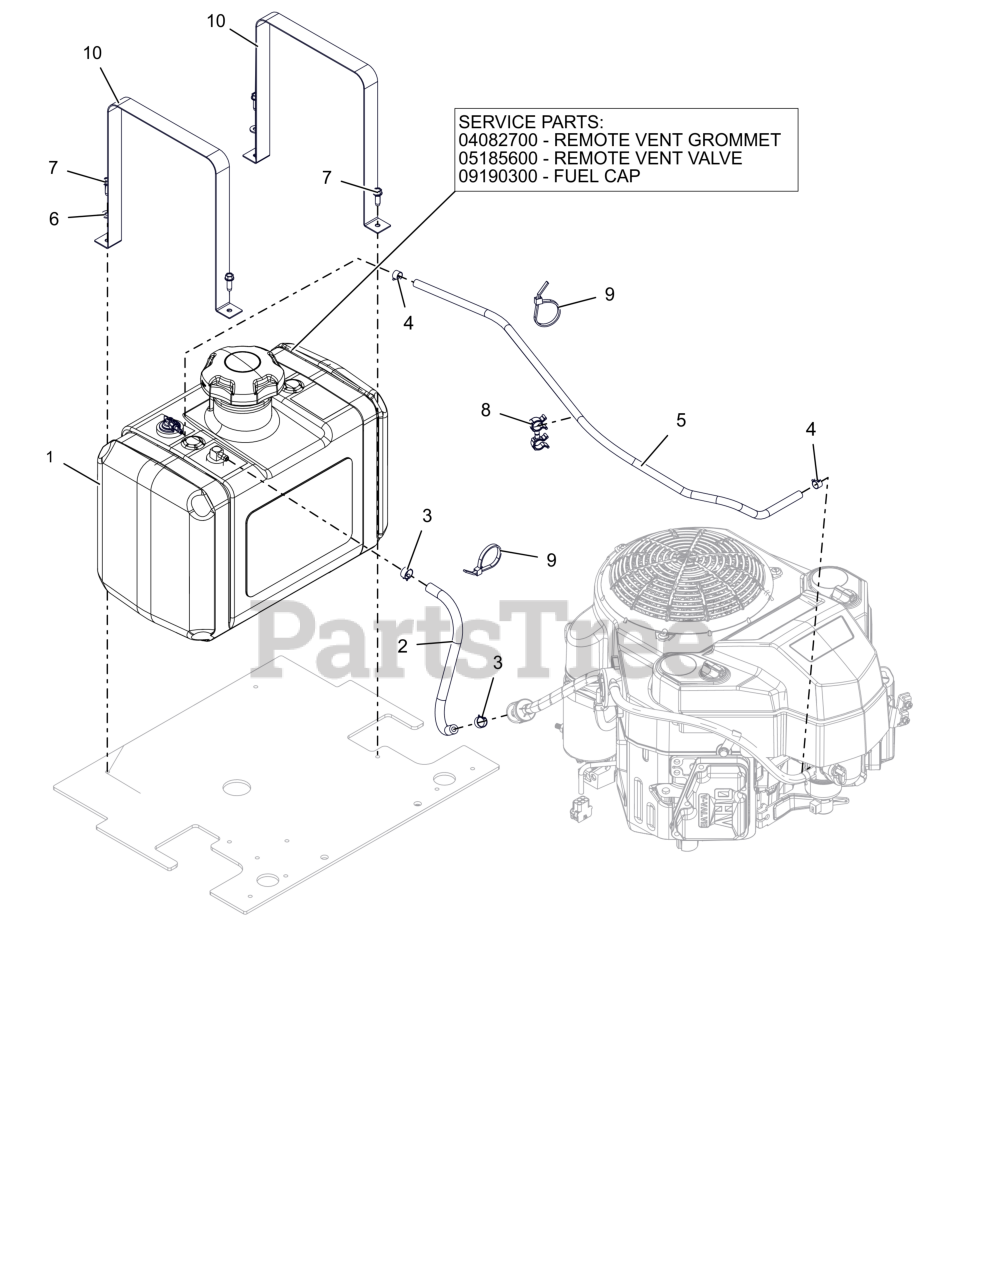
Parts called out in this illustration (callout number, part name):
1	ASM, FUEL TANK 5-GAL (SEMCO)
1	GROMMET, REMOTE VENT NITRILE
1	VALVE, COMBINATION VENT 3/16
1	CAP, FUEL - 3.50 RATCHET INLET VENT
2	HOSE, .25 LOW-PERM BULK GAS, SOLD BY THE INCH
3	CLAMP, FUEL LINE
4	CLAMP-HOSE, SPRING .188
5	HOSE, .188 30R7 BULK, SOLD BY THE INCH
6	WSHR,FLT .281X.625X.065 ZCC
7	SCR,TAP .25-20X.75 HWH TR ZCC
8	CLIP, 360 DEGREE SWIVEL .500 DIA HOSE
9	CABLE TIE LG 5-1/2
10	STRAP, TANK (BLACK)
